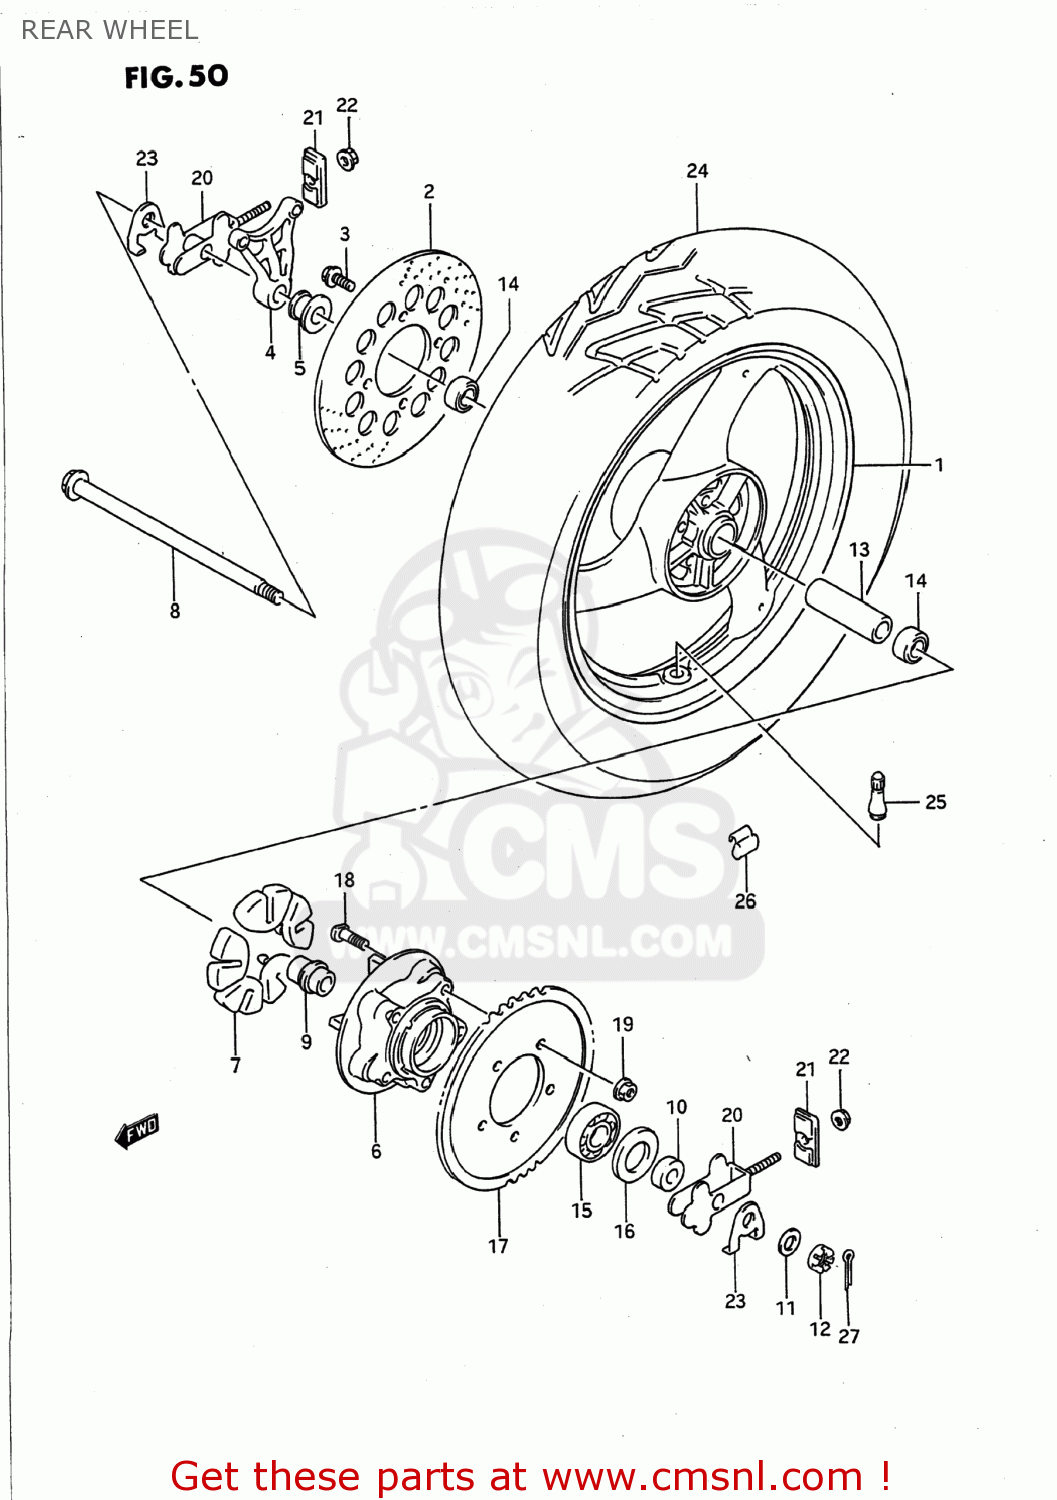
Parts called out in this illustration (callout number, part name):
1	WHEEL,RR(MT3.50X17)
2	DISC,RR BRAKE
3	BOLT
4	BRACKET,RR,CALIPER
5	SPACER,RR AXLE,R
6	DRUM,RR SPROCKET
7	ABSORBER,RR HUB SHOCK
8	AXLE,REAR
9	RETAINER,RR SPROCKET DRUM
10	SPACER,RR AXLE,L
11	WASHER(17X30X3)
12	NUT
13	SPACER(17.5X25X88)
14	BEARING
15	BEARING(25X62X17)
16	SEAL,OIL(35X62X8)
17	SPROCKET,RR(NT:39-520)
18	BOLT
19	NUT
20	ADJUSTER,CHAIN
21	PLATE,CHAIN ADJUSTER GUIDE
22	NUT
23	WASHER,CHAIN ADJUSTER
24	TIRE,T/L(130/70-17 62H)
25	VALVE,TIRE
26	BALANCER,WHEEL
27	PIN,COTTER
